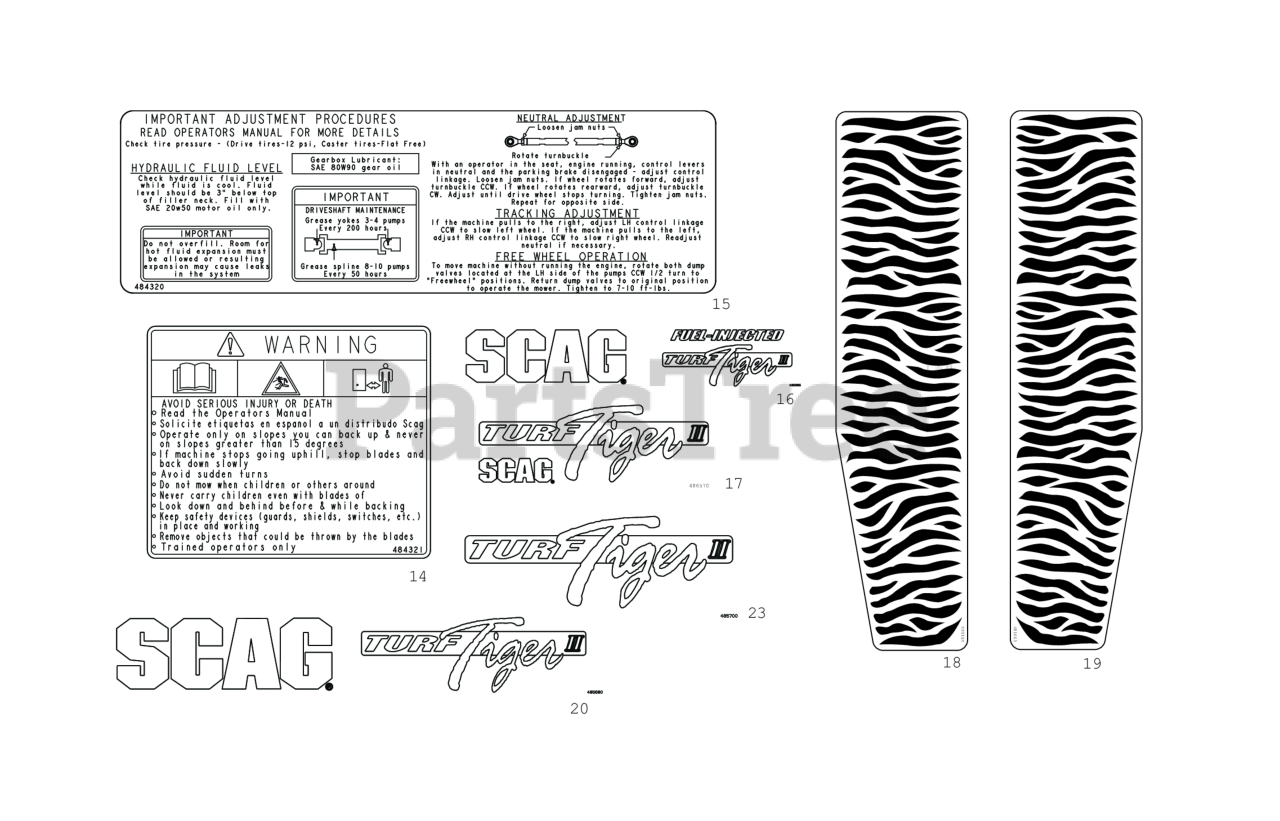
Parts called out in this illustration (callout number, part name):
1	Decal, Danger-Spinning Blades
14	Decal, Start/Drive Procedure
15	Decal, Checks and Adjustments
16	Decal, Hood - STTII Fuel Injected
17	Decal, Turf Tiger II
18	Decal, Stripes-RH
19	Decal, Stripes-LH
20	Decal, Hood - STTII
23	Decal, Turf Tiger II
